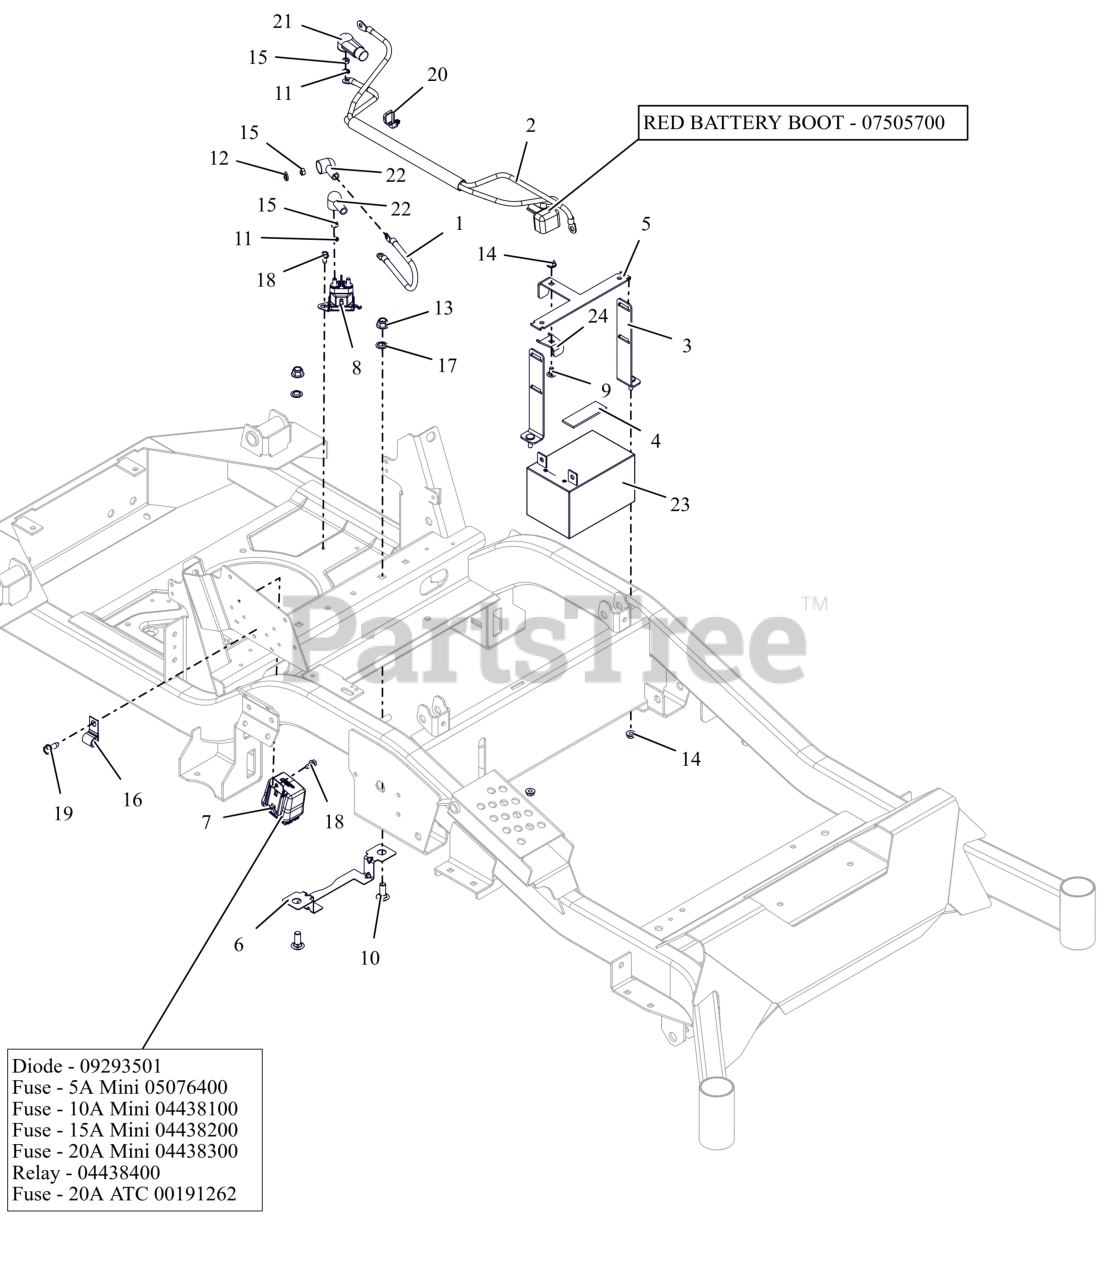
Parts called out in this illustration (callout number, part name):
1	CABLE, POS W/(2)1/4 RING 9.0LG
2	HARNESS, BATTERY HD
2	INSULATOR
3	WMT,BATTERY MOUNT HOLD DOWN
4	PAD,RBR 1.0"X3.0" W/ADHESIVE
5	BRKT, BATTERY TIE DOWN
6	GUARD, ELECTRICAL HARNESS
7	HARNESS, WIRE
7	DIODE, CONNECTOR SHELL
7	FUSE, 5 AMP MINI-ATC
7	FUSE,10 AMP MINI-ATC
7	Fuse, 15 AMP MINI-ATC
7	FUSE,20 AMP MINI ATC
7	RELAY,MICRO5 TERML W/RESISTOR
7	FUSE, 20 AMP BLADE S/O
8	SOLENOID, STARTER (SEALED)
9	BLT, RHSN .25-20X.500 G5 ZCC
10	BLT, RHSN .38-16X1.00 G5 ZCC
11	WSHR,LK-EXT.262X.502X.026 ZCC
12	WSHR,LK-REG .312X.078 ZCC
13	NUT,NYL-FLG .38-16 GF ZCC
14	NUT-LK-TOP-FLG .250-20 GF ZCC
15	NUT-STD M6-1.0 ZCC
16	J-CLAMP
17	NUT-PUSH .38 DIA. PAL ZINC
18	SCR-TAP .25-20X.50 HWH ZCC
19	SCR,TAP .312-18X.75 HWH TR ZCC
20	CABLE TIE W/ TREE (.25 HOLE)
21	BOOT, .65ID POS
22	BOOT, EYELET TERMINAL
23	BATTERY, 12V 12AH -190CCA
24	BRKT, BATTERY HOLD
